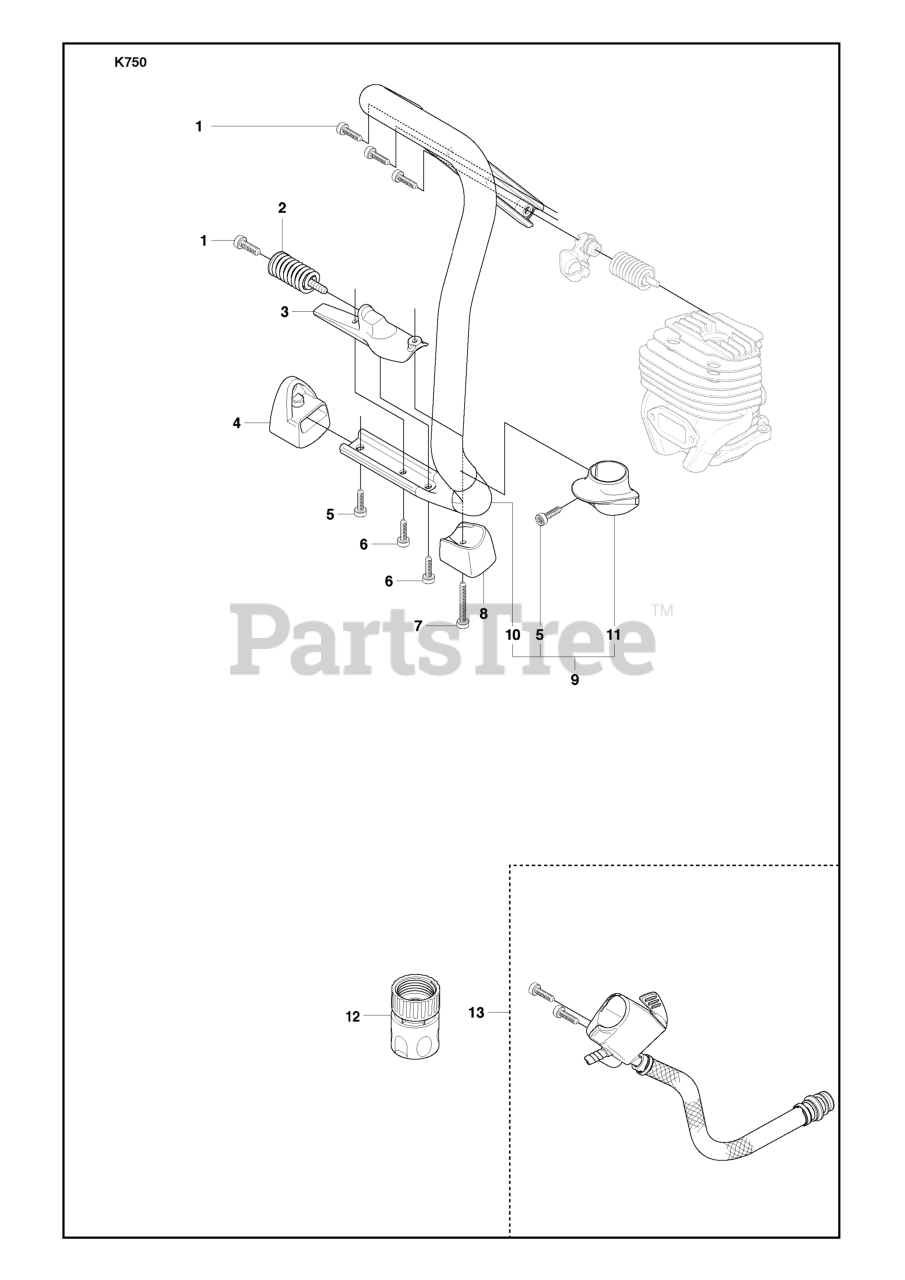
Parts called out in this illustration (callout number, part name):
2	ANTIVIBRATION ELEMENT
3	%SPRING RETAINER
4	GROUND SUPPORT
8	GROUND SUPPORT
9	HANDLE FRONT ASSY
10	FRONT HANDLE
12	FEMALE QUICK COUPLER
12	COUPLER, 1/2" HOSE W/STOP ORIG
13	HOSE KIT, WET CUT KIT, HANDLE
